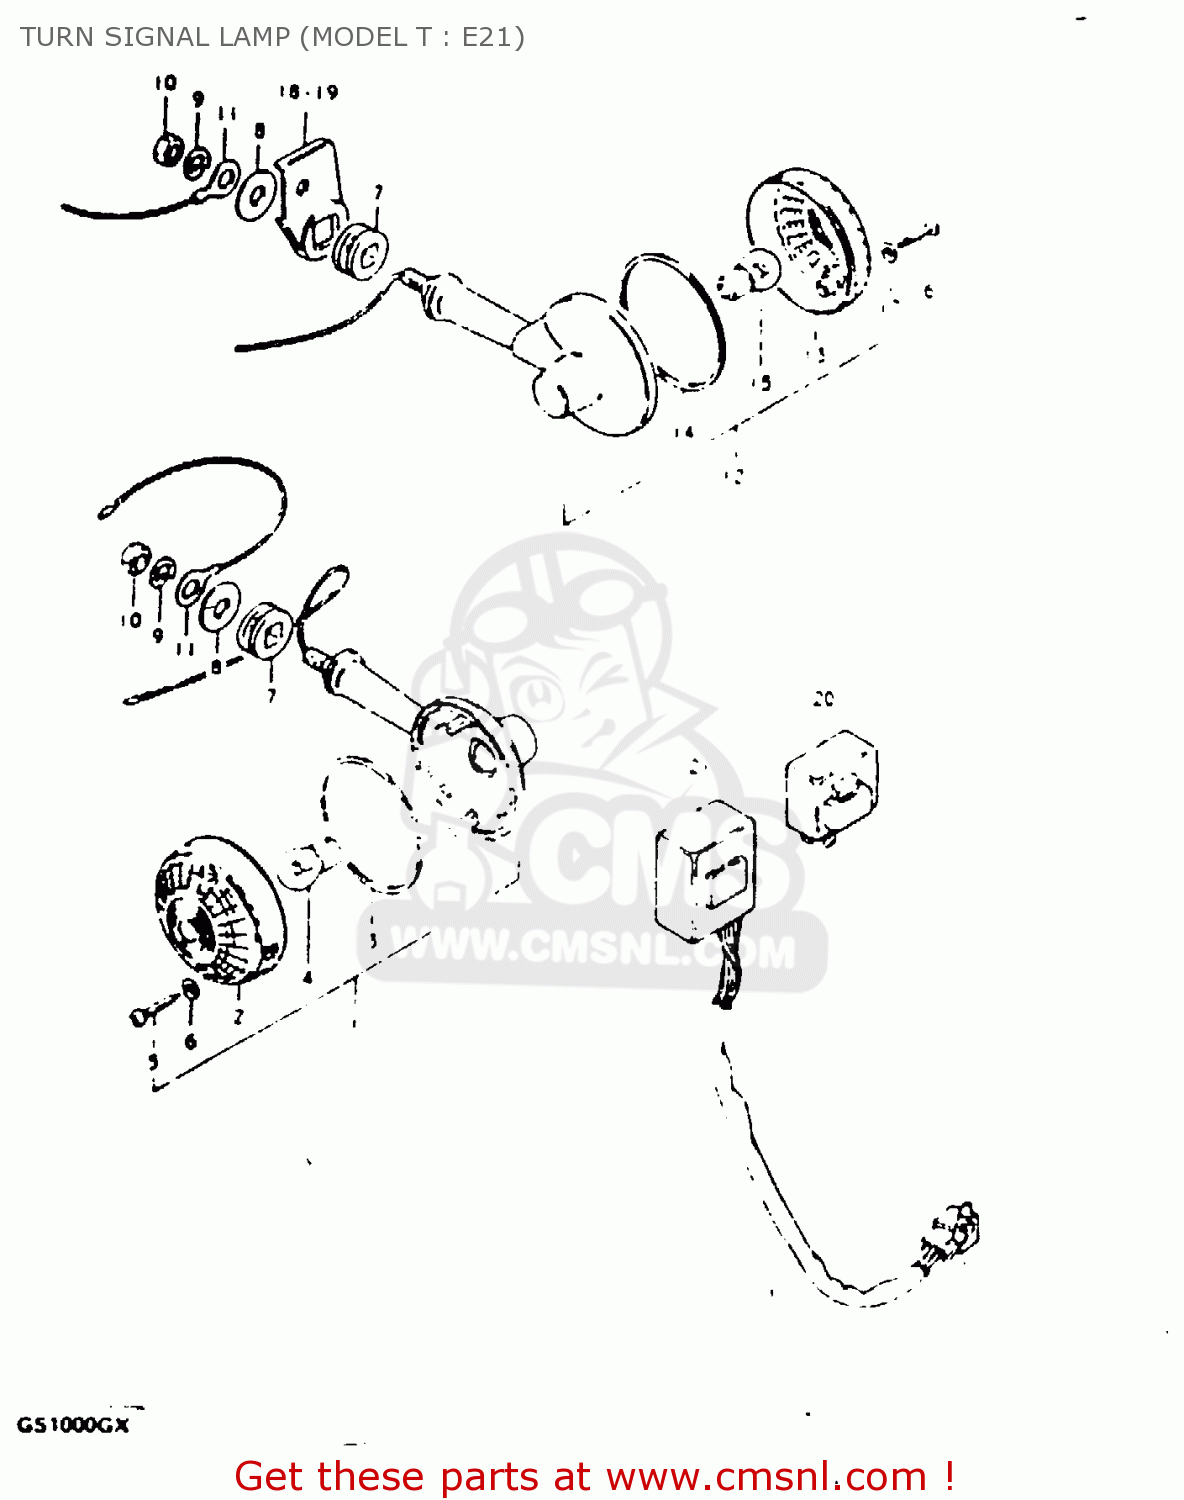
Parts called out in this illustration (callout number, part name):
1	LAMP ASSY, FRONT TURN SIGNAL
2	LENS
3	GASKET (NAS)
4	BULB 12V 21W
5	BOLT
6	GASKET (NAS)
7	CUSHION
8	WASHER
9	LOCK WASHER
10	NUT
11	LEAD WIRE,EARTH
12	LAMP ASSY, REAR TURN SIGNAL
13	LENS
14	GASKET (NAS)
15	BULB 12V 21W
16	BOLT
17	GASKET (NAS)
18	BRACKET,RR TURNSIGNAL LAMP,R
19	BRACKET,RR TURNSIGNAL LAMP,L
20	RELAY ASSY,TURNSIGNAL
21	UNIT,TURN SIGNAL CONTROL
